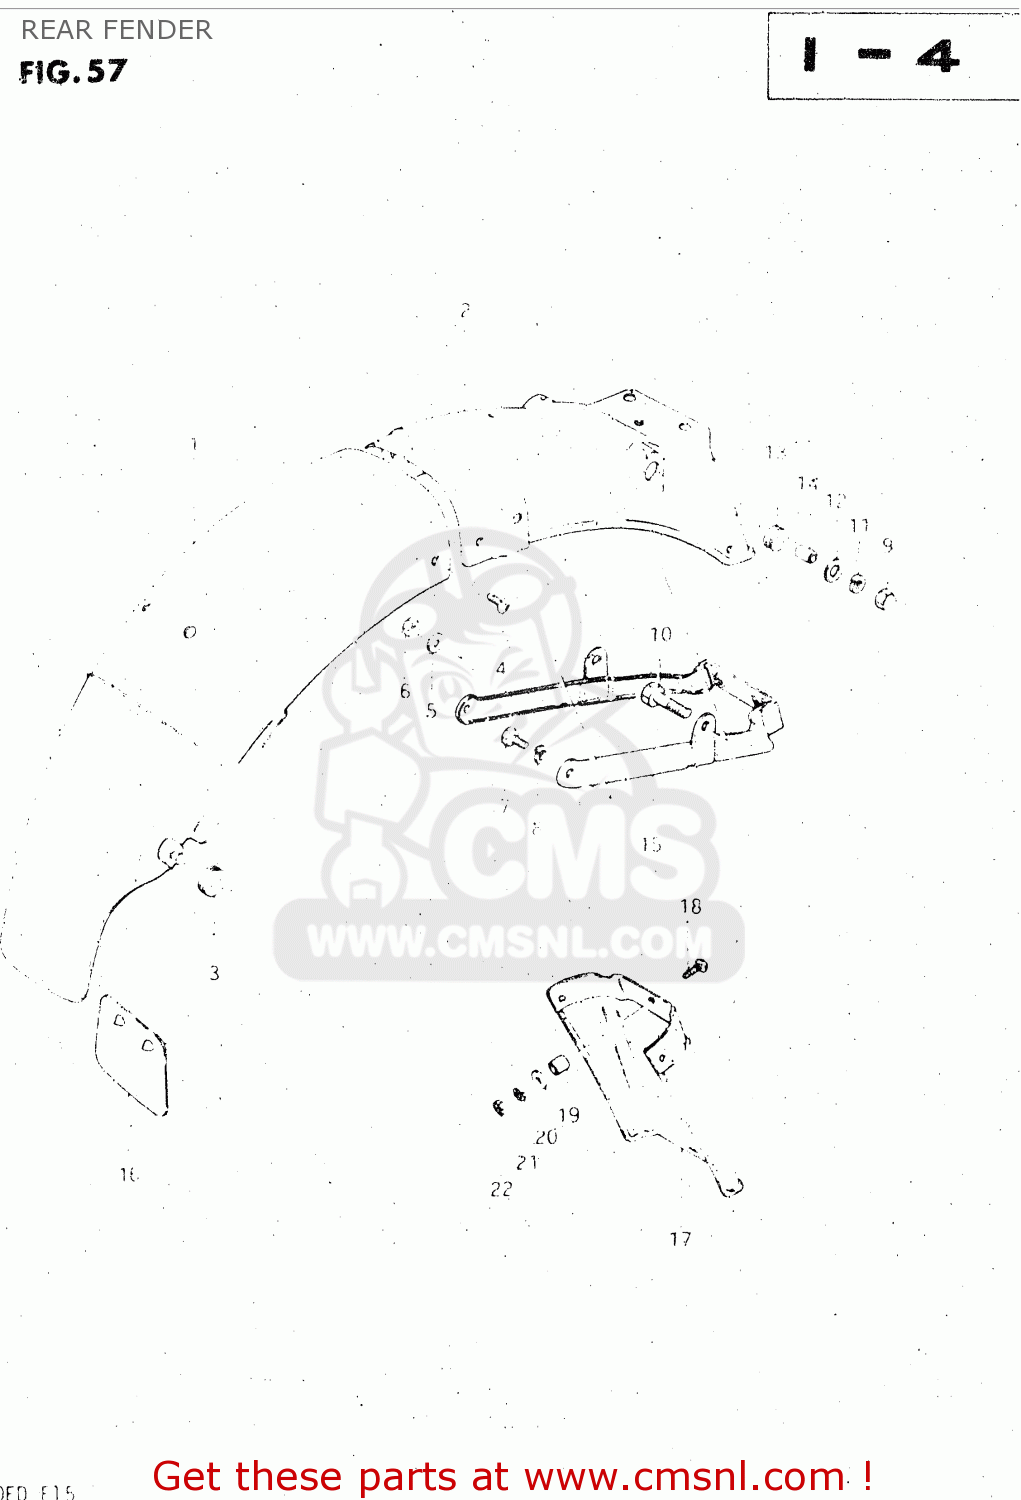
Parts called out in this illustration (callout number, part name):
1	BODY,RR FENDER FR
2	FENDER,REAR
3	CUSHION
4	SCREW
5	WASHER (5.5X16X1.2)
6	NUT
7	BOLT, UPPER
8	LOCK WASHER
9	NUT
10	BOLT 8X45
11	LOCK WASHER
12	WASHER
13	CUSHION
14	SPACER (8.2X12X7.5)
15	REINFORCEMENT,REAR FENDER
16	GUIDE,RR FENDER MUD
17	EXTENSION, REAR FENDER
18	SCREW (6X15)
19	SPACER(6.2X8.3X5.7)
20	WASHER(6.5X18X1)
21	LOCK WASHER
22	NUT
